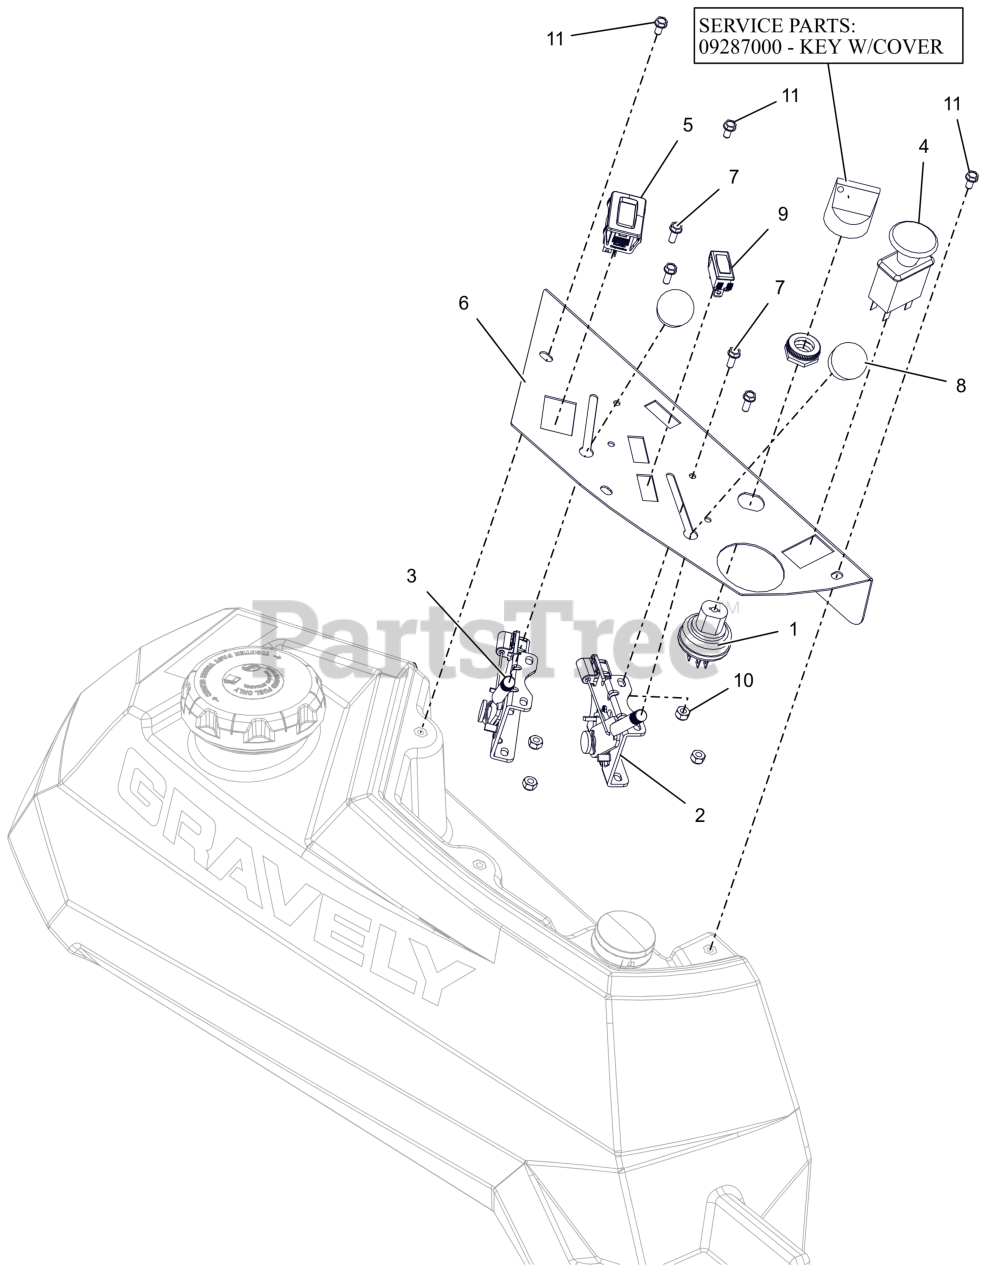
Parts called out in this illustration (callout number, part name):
1	SWITCH, IGNITION
1	KEY, W/ SHIELD
2	CABLE, PRO-CONTROL 28.50
3	CABLE, PRO-CONTROL 31.50"
4	SWITCH, CLUTCH
5	HOUR METER
6	PT100 CONTROL PANEL - RED
7	BLT, HWH #10-24X.50 ZCC
8	KNOB-CONTROL-BLACK .38-16X.50
9	LIGHT, INDICATOR (RED)
10	NUT-LK-NYL #10-24 G2 ZCC
11	SCR-MCH 10-24X.38 HWHSTAINLESS
